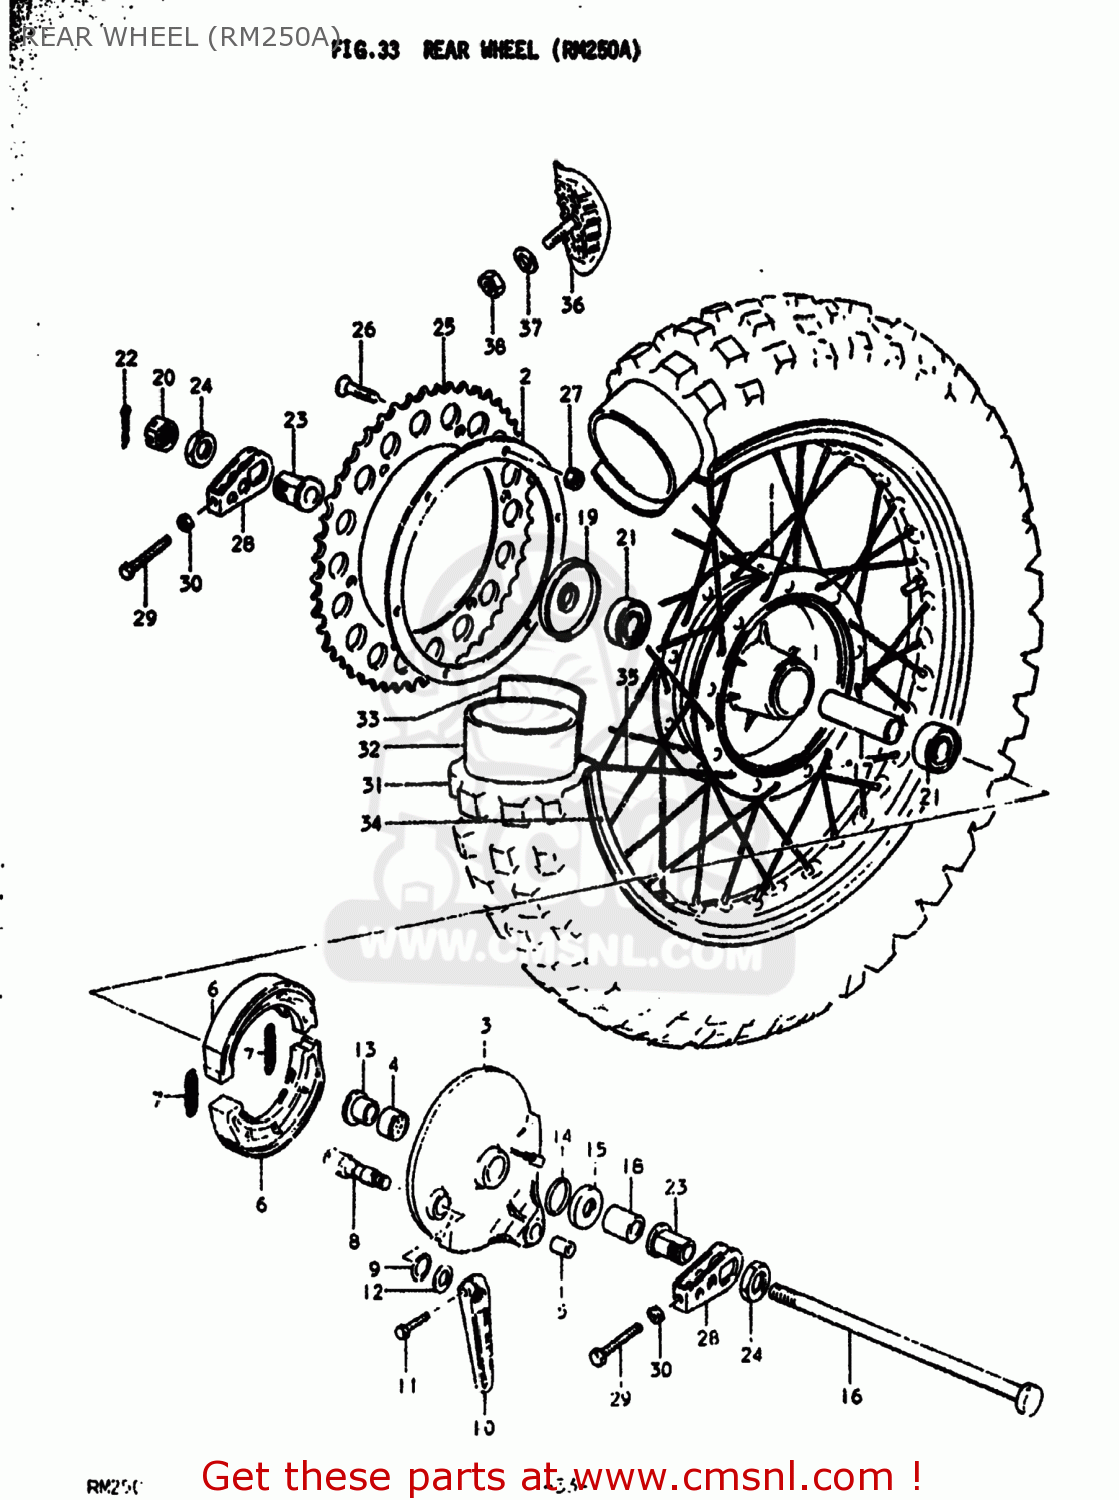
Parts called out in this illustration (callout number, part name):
1	HUB COMP,REAR
2	SPACER / SHIM
3	PANEL,REAR HUB
4	BUSHING
5	PIN,CALIPER BRACKET
6	SHOE,BRAKE
7	SPRING
8	CAM,FRONT BRAKE
9	O-RING,BOSS
10	LEVER,FRONT BRAKE CAM
11	BOLT
12	WASHER (15X24X1.6)
13	BUSHING
14	O-RING
16	AXLE,REAR
17	SPACER,REAR HUB BEARING
18	SPACER
19	SPACER,REAR AXLE
20	NUT
21	BEARING
22	PIN 30X40
23	SPACER,CHAIN ADJUSTER
24	NUT
25	SPROCKET,REAR
26	SCREW
27	NUT
28	ADJUSTER,CHAIN
29	BOLT
30	NUT
31	TIRE
32	TUBE ASSEMBLY,WHEEL,INNER
33	PROTECTOR,WHEEL,INNER
34	RIM,REAR WHEEL
35	SPOKE SET,REAR
36	STOPPER,BEAD
37	WASHER
38	NUT
